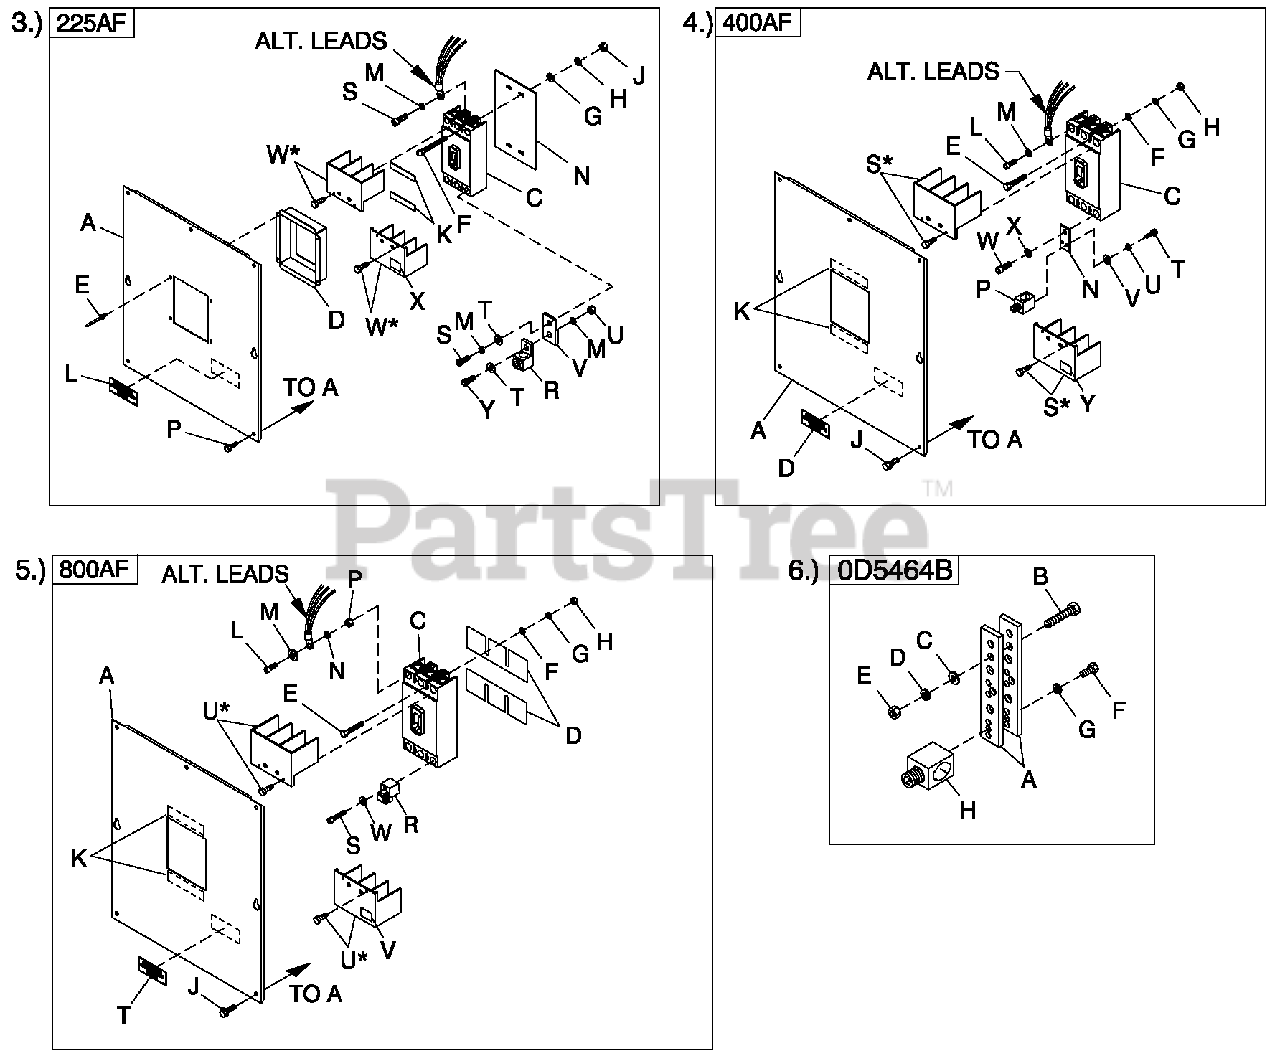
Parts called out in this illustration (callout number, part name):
A	COVER CBC5 225AF
C	CIRCUIT BREAKERS 200A FRAME
D	COVER CB DISH 225AF
E	RIVET POP .125 X .275 SS
F	SCREW RHM #8-32X3-1/4
G	WASHER FLAT #8 ZINC
H	WASHER LOCK #8-M4
J	NUT HEX #8-32 STEEL
K	TAPE ELEC 1/2 FOAM
L	DECAL CUSTOMER CONNECT INSIDE
M	WASHER LOCK M8-5/16
N	INSULATOR CB225AF
P	SCREW THF M6-1 X 16 N WA Z/JS
R	LUG SLDLSS 300 MCM-6 AL/CU
S	SCREW SHC M 8 -1.25X20G 8
T	WASHER FLAT 5/16-M8 ZINC
U	NUT HEX M8-1.25 G8 CLEAR ZINC
V	BUS BAR 200A LUG ADAPTOR
W	TERMINAL COVER CB
X	DECAL TERMINAL SHOCK HZD BI
Y	SCREW SHC M8-1.25 X 25 G12.9
A	COVER CBC5 400AF
C	CIRCUIT BREAKERS 400A FRAME
D	DECAL CUSTOMER CONNECT INSIDE
E	SCREW RHM 1 0 -3 2X4
F	WASHER FLAT #10 ZINC
G	WASHER LOCK #10
H	NUT HEX #10-32 STEEL
J	SCREW THF M6-1 X 16 N WA Z/JS
L	SCREW SHC M10-1.5X25G12.9
M	WASHER LOCK M10
N	BUS BAR CB ADAPTER 225-400 A
P	LUG SLDLSS 600/250-1/0 X 1/4-28
R	WASHER FLAT 3/8-M10 ZINC
S	TERM COVER CB
T	SCREW HHC 1/4-28 X 1/2 G5
U	WASHER LOCK M6-1/4
V	WASHER FLAT 1/4-M6 ZINC
W	SCREW SHC M10-1.5X25G12.9
X	WASHER LOCK M10
Y	DECAL TERMINAL SHOCK HZD BI
A	COVER CBC5 800AF
C	CIRCUIT BREAKERS 800A FRAME
D	INSULATOR CB800AF
E	SCREW RHM 1/4-20X3-1/2
F	WASHER FLAT 1/4-M6 ZINC
G	WASHER LOCK M6-1/4
H	NUT HEX 1/4-20 STEEL
J	SCREW THF M6-1X16 N WA Z/JS
L	SCREW SHC M10-1.50X 40 G12.9
M	WASHERFLAT 3/8-M10ZINC
N	WASHER LOCK 3/8
P	NUT HEX M10-1.5 G8YEL CHR
R	LUG SLDLSS 3/0-400X3 MCM AL/CU
S	SCREW SHC M6-1.0X50G8.8
T	DECAL CUSTOMER CONNECT INSIDE
U	TERM COVERVITZROTECH 400AF CB
V	DECALTERMINALSHOCK HZD BI
W	WASHER LOCK M6-1/4
A	BUS BAR NEUTRAL BLOCK 390
B	SCREW HHC M8-1.25 X 45 G8.8 FT
C	WASHERFLAT 5/16-M8ZINC
D	WASHER LOCK M8-5/16
E	NUT HEX M8-1.25G8YELCHR
F	SCREW HHC 1/4-28 X 3/4 G5
H	LUG SLDLSS 600/250-1/0X1/4-28
